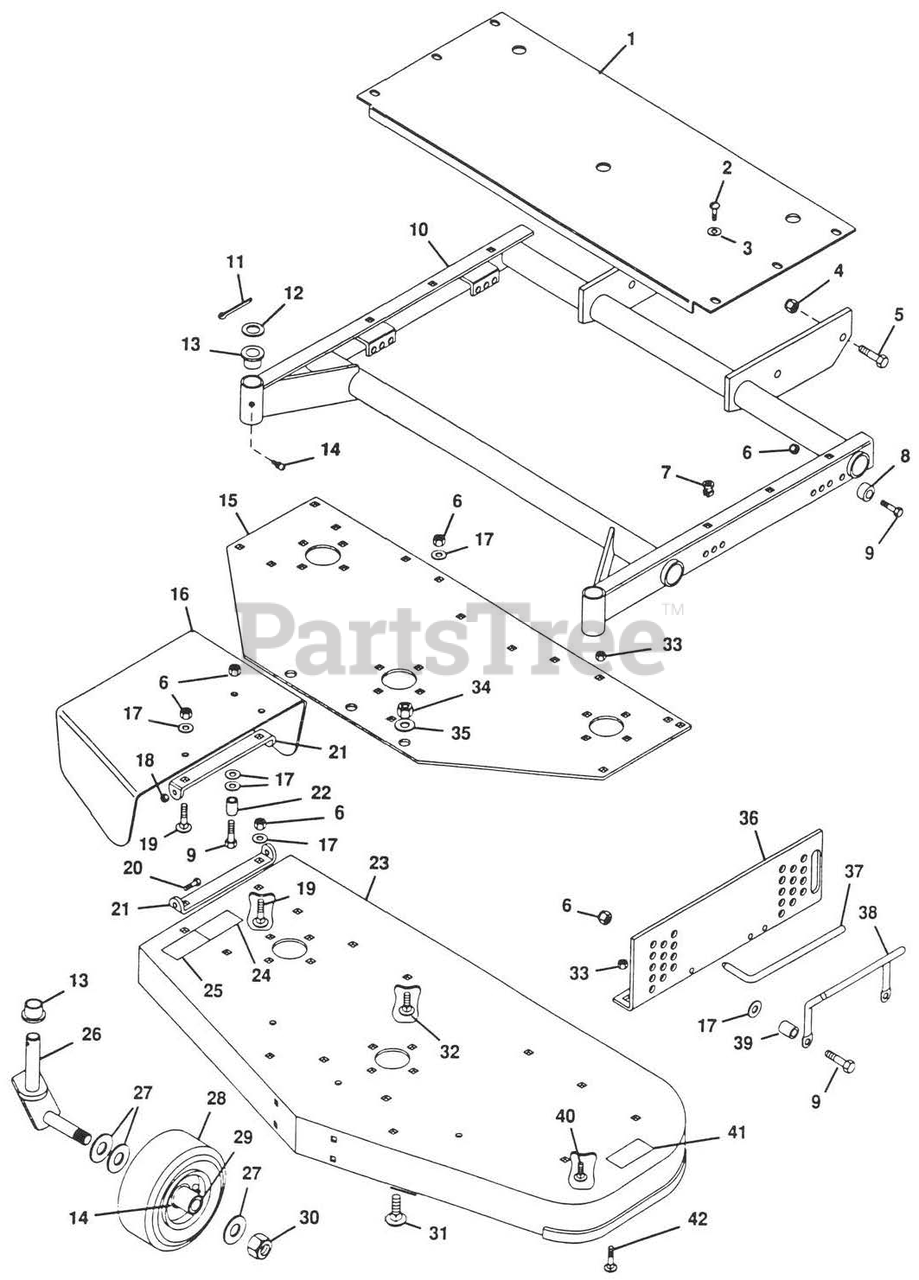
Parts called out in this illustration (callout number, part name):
1	GUARD - 50" MOWER BELT
2	SCREW-TAPPING HEX SLOTTED HEAD
3	WASHER-FLAT-STEEL .281 X .625 X .065
4	NUT-LOCKING-NYLON .62-11 X 1.50
5	BOLT-HEX .62-11 X 1.50
6	NUT-LOCK .375-16
7	BROMMET-PLASTIC
8	BRUSHING-STEEL .391 X .626 X .670
9	BOLT-HEX .38-16 X 1.50
10	WELDMENT - MOWER FRAME - PRO-50
11	FPIN-COTTER .187 X 1.50
12	WASHER - HARDENED
13	BUSHING-FLANGE-NYLON 1.020 X 1.385 X .75 X 1.75
14	FITTING - LUBE .25-28 X .256
15	PLATE - SUPPORT
16	SHIELD - SAFETY EXTERNAL 50" MOWER
17	WASHER-FLAT-STEEL .406 X .812 X .065
18	NUT-LOCKING-NYLON .250-20 GRADE 2
19	BOLT-ROUND HEAD SQUARE NECK .38-16 X 1.0
20	BOLT-HEX .38-16 X 1.38
21	BRACKET - CHUTE
22	BUSHING-SLEEVE .407 X .625 X .750
23	WELDMENT - 50" MOWER FABRICATED
24	DECAL - DANGER HAND
25	G-DECAL-WARNING EYE
26	WELDMENT-CASTOR-FORK
27	WASHER-FLAT .812 X 1.496 X .134
28	WHEEL-GAUGE
29	BEARING-GAUGE WHEEL
30	NUT-LOCKING-NYLON .75-10 GRADE 2
31	BOLT-ROUND HEAD SQUARE NECK .50-13 X 1.00
32	BOLT-ROUND HEAD SQUARE NECK .38-16 X .75 GRADE 1
33	NUT-LOCKING-NYLON W/INSERT .312-18 GRADE 2
34	NUT-LOCKING-NYLON .50-13 GRADE 5
35	WASHER-FLAT-STEEL .531 X 1.250 X .100
36	BRACKET - MOWER SIDE SUPPORT LEFT HAND
37	PIN - MOWER LOCKING
40	BOLT-ROUND HEAD SQUARE NECK .31-18 X .62
41	DECAL - DANGER FOOT
42	BOLT-ROUND HEAD SQUARE CECK .31-18 X 1.00
